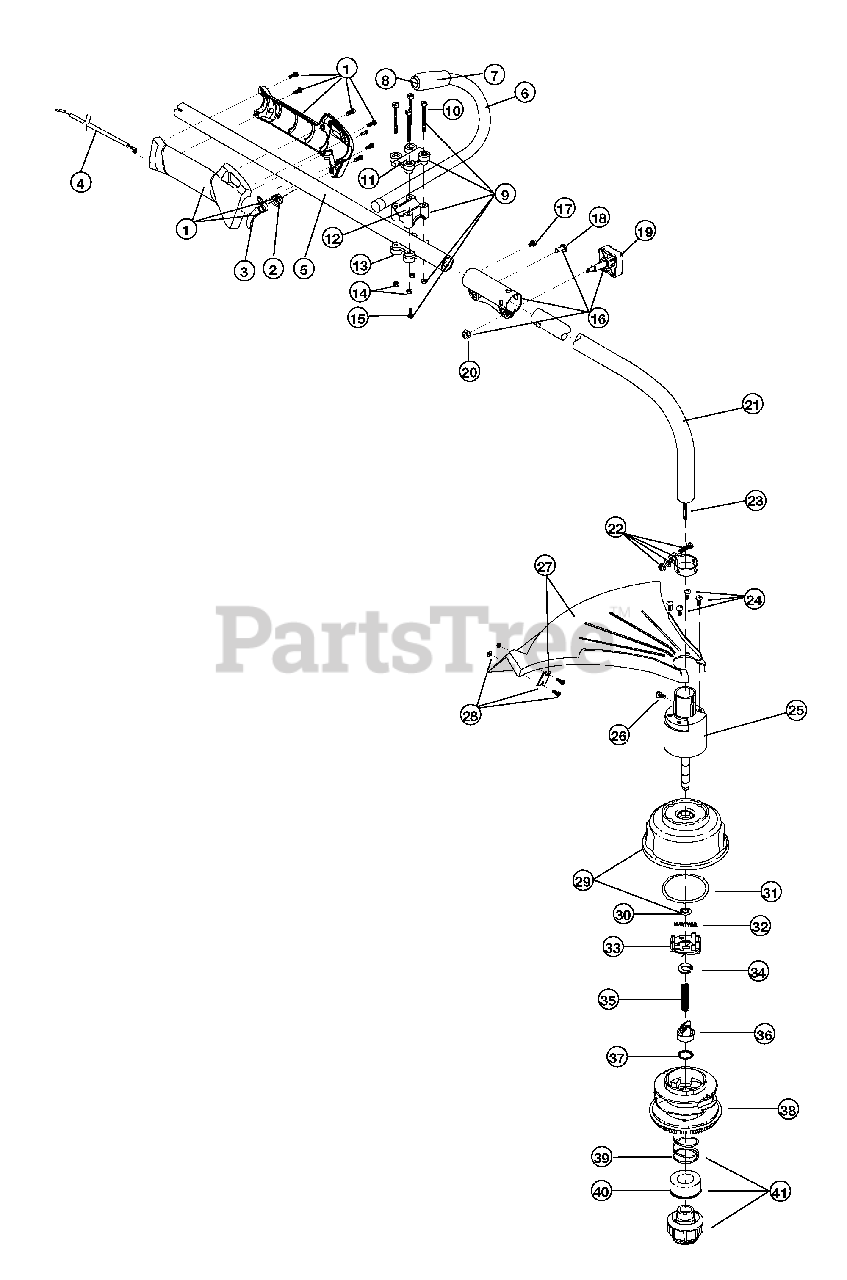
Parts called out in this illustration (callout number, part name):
1	Throttle Housing and Trigger Assembly
2	Throttle Trigger Spring
3	Throttle Trigger
4	Throttle Cable
5	Upper Drive Shaft Housing
6	J-Handle Assembly
8	Tube Closure
9	Handle Bracket Assembly
11	Upper Handle Clamp
12	Middle Handle Clamp
13	Lower Handle Clamp
15	Anti-Rotation Screw
16	Click-Link Coupler
19	Adjustment Knob
20	Knob Retaining Nut
21	Lower Drive Shaft Housing
22	Lower Clamp Assembly
23	Lower Flexible Drive Shaft
24	Shield Mounting Screw
25	Gearbox
26	Anti-Rotation Screw
27	Shield and Blade Assembly
28	Blade Assembly
29	Outer Spool and Eyelet Assembly w/ Retainer
30	Retainer
31	Thrust Washer
32	Small Spring
33	Slider
36	Plunger
38	Inner Reel
39	Large Spring
40	Foam Seal
41	Bump Head Knob Assembly w/Spring & Foam Seal
